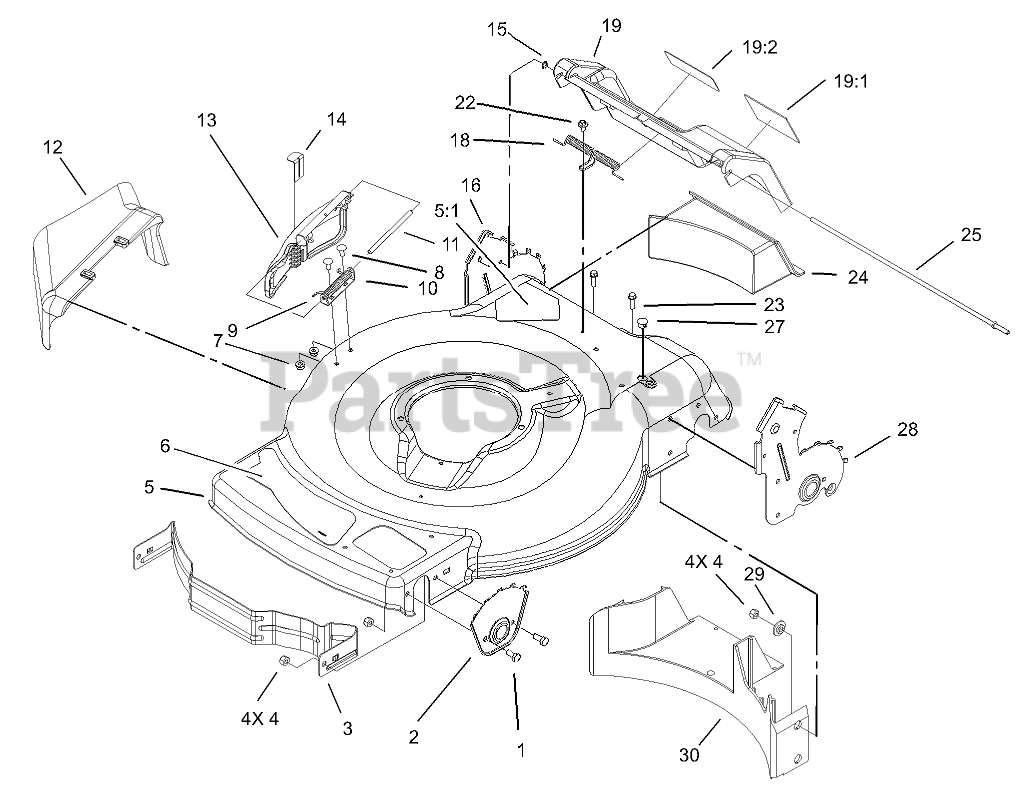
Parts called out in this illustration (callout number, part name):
1	SCREW-HH
2	Plate-HOC, Front
3	Baffle-Front
4	NUT-LOCK, NI
5	Housing (only on: 20018)
5	Housing (only on: 20014)
5:1	Decal-Danger, Cut Finger (only on: 20014)
5:1	Decal-Danger (only on: 20018)
6	Decal-Deck
7	NUT-HHF
8	SCREW-CARR
9	SPRING-TORSION
10	BRACKET-COVER
11	ROD-COVER
12	CHUTE-DISCHARGE, SIDE
13	Door-Discharge, Side
14	Lever-Latch
15	NUT-PUSH
16	RH REAR HOC PLATE ASM (only on: 20013)
18	Spring-Door, Rear
19	Door (only on: 20014)
19	Door (only on: 20018)
19:1	Decal-Warning (only on: 20014)
19:2	Decal-Warning, Door (only on: 20018)
19:2	Decal Warning (only on: 20014)
22	SCREW AND WASHER ASM
23	SCREW-HWH
24	Plug-Discharge, Rear
25	Rod-Pivot, Rear Door
27	Plug-Dome
28	LH REAR HOC PLATE ASM (only on: 20013)
29	Washer-Stepped
30	Baffle-Rear
